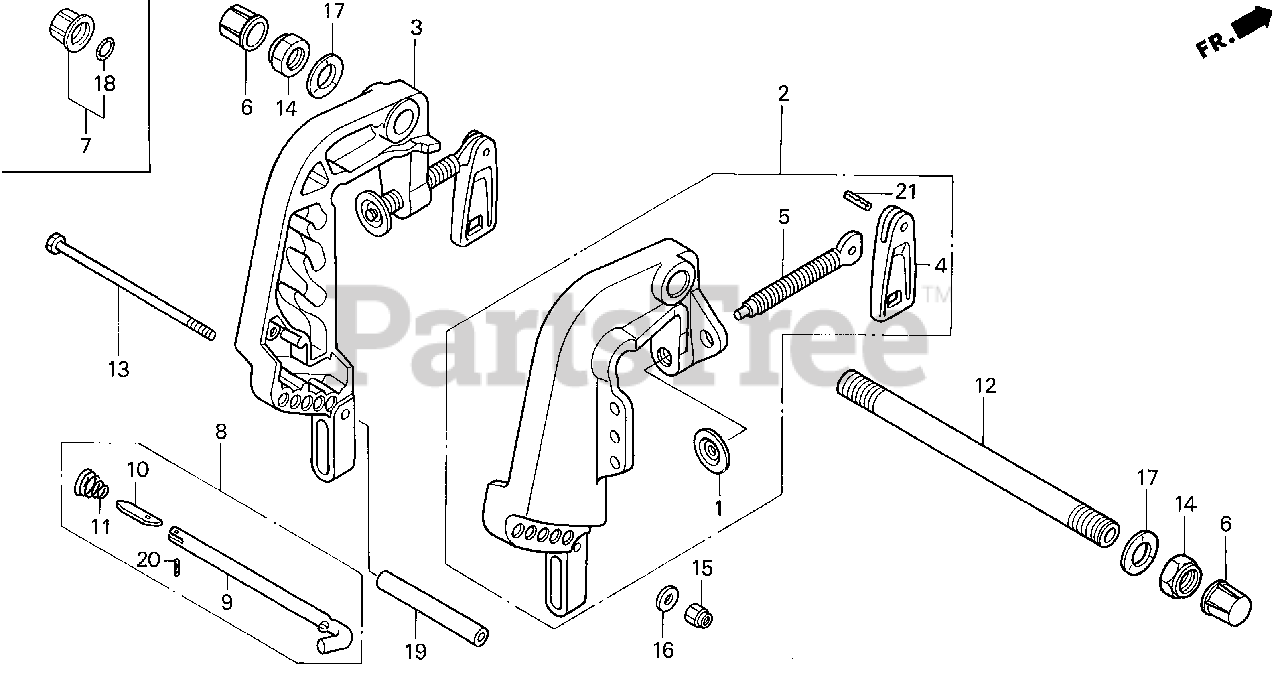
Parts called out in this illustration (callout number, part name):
1	PLATE, PUSH
2	BRACKET, R. STERN *NH282MU* (OYSTER SILVER METALLIC-U)
3	BRACKET, L. STERN *NH282MU* (OYSTER SILVER METALLIC-U)
4	GRIP, CLAMP *NH282MU* (OYSTER SILVER METALLIC-U)
5	SCREW, CLAMP
6	CAP, TILTING BOLT
8	ROD, ADJUSTING
9	ROD, ADJUSTING
10	STOPPER, ROD
11	SPRING, ROD ADJUSTING
12	SHAFT, TILTING
13	BOLT, HEX. (8X163)
14	NUT, SELF-LOCK (7/8-14UNF)
15	NUT, SELF-LOCK (8MM)
16	WASHER, PLAIN (8MM)
17	WASHER, WAVE (22MM)
18	O-RING (15.54X2.26)
19	COLLAR, DISTANCE
20	PIN, SPRING (2.5X8)
21	PIN, SPRING (4X14)
